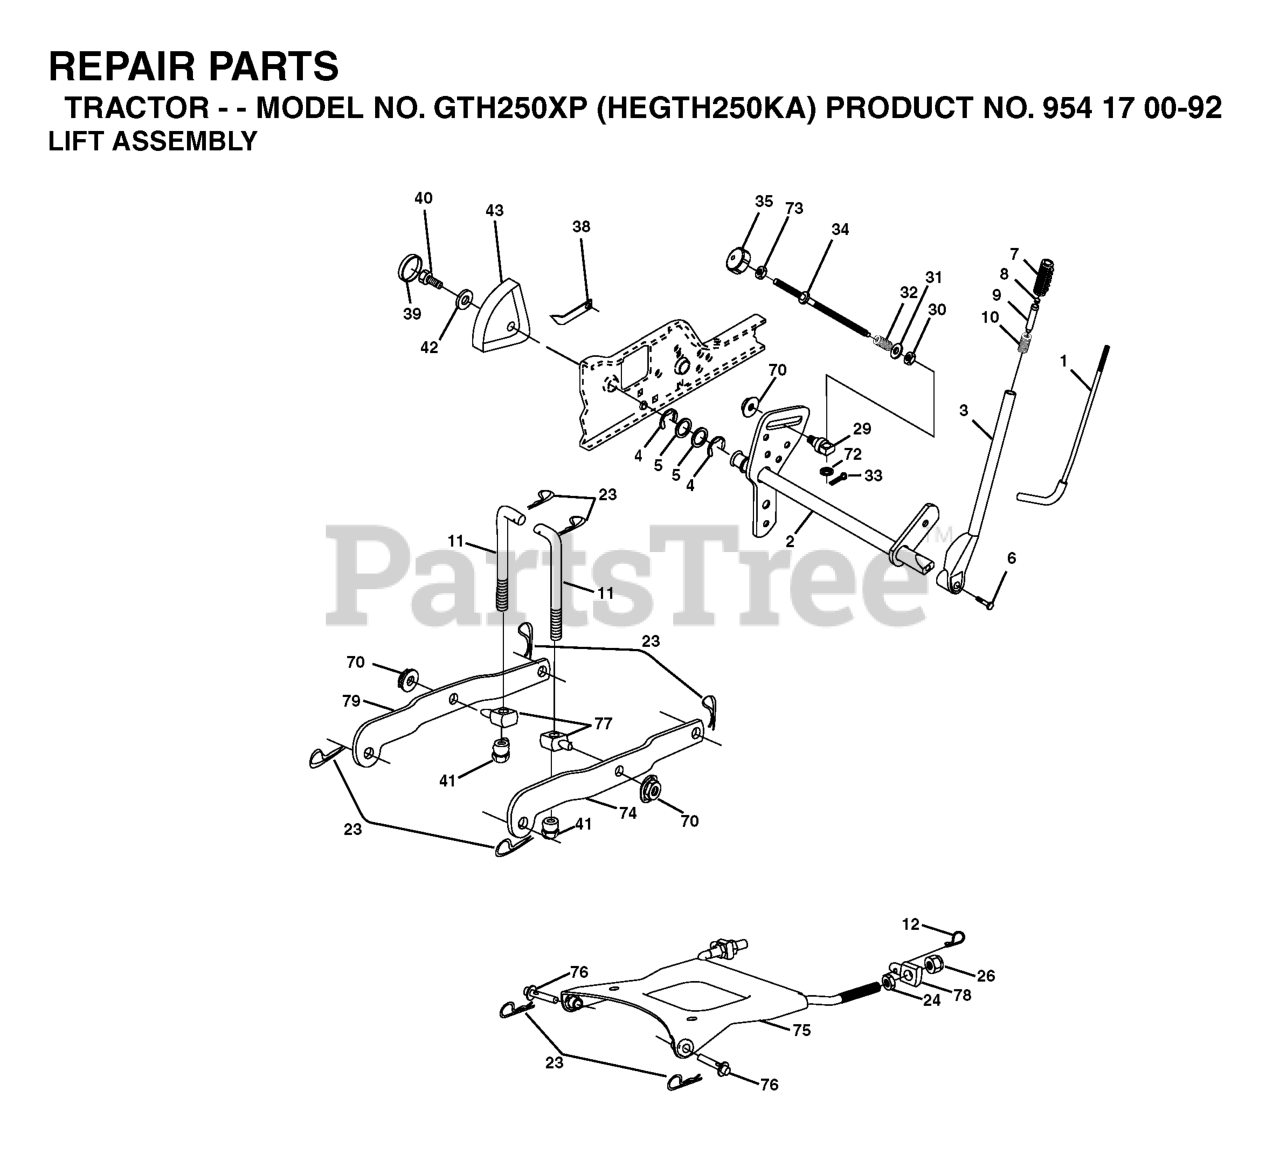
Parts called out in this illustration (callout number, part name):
1	LEVER ROD LT
2	SHAFT ASM., LIFT VGT
3	LEVER ASSY-LIFT RH
5	Washer 29/32 x 1 - 1/4 x 16 Ga.
6	Bolt, Fin Hex 3/8-16 x 1-1/12
7	GRIP HANDLE
8	PLUNGER BUT KIT
9	PLUNGER BUT KIT
10	SPRING 0.620D X 2.125
11	LIFT LINK
12	SPRING RETAINER
23	RETAINER-SPRNG RB
24	NUT.HEX.JAM.1/2-13
26	NUT LTV
32	SPRING.COMP.INF.H
33	COTTER PIN
34	ROD.LIFT.ADJUSTABLE
35	KNOB INF 3/8-16
38	POINTER, HEIGHT INDICATOR(2 2)
40	SCREW 5/16-18X1
41	NUT, LIFT LINK 7/16-20
43	HEIGHT INDICATOR
70	NUT
72	NUT PUSH M
73	NUT
74	ARM SUSP REAR RH
75	PLATE ASM SUSP FRONT
76	PIN.FLANGE
79	ARM SUSP. REAR LH
80	WASHER
